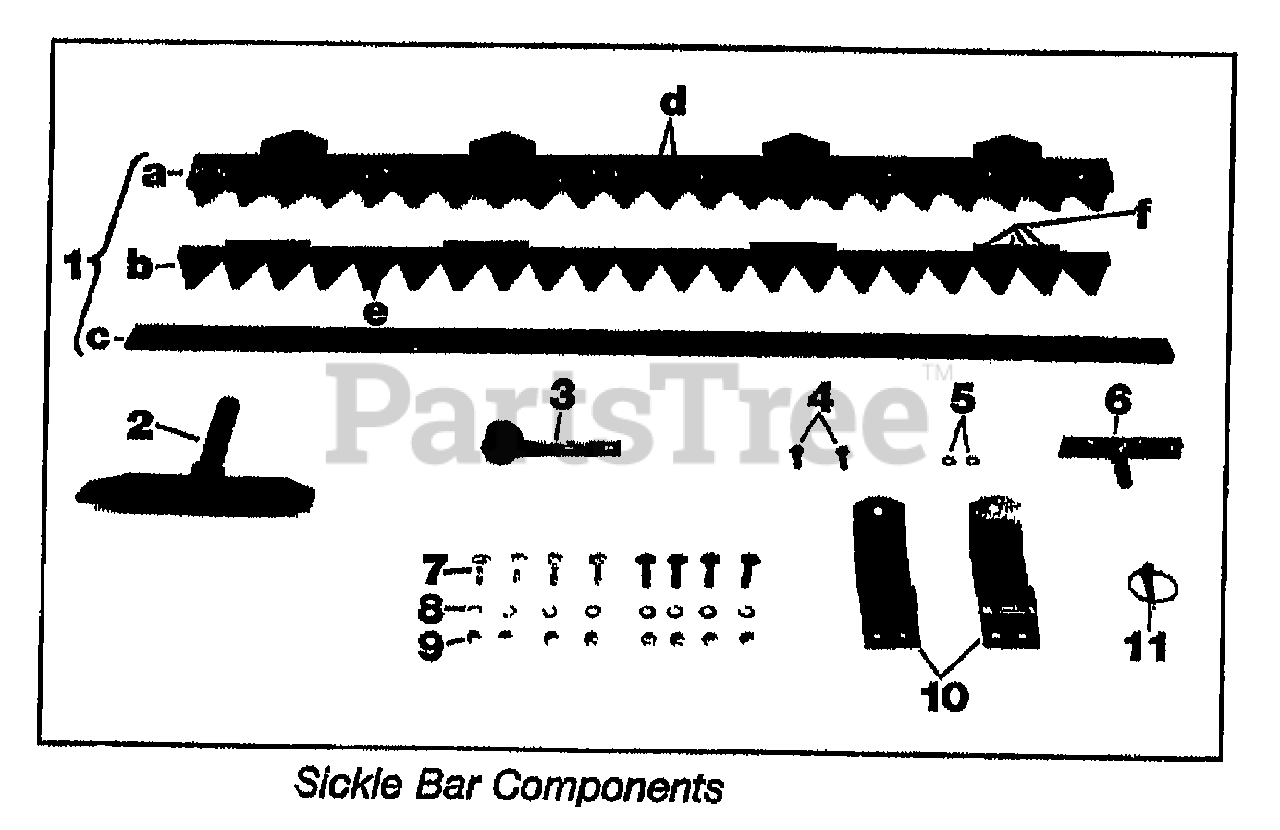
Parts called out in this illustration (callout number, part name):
1	BAR-LEDGER ASM W/BLADES
1	ASSM-38" KNIFE T/B SICKLEBAR (100CM)
1	COVER BLADE KNIFT - 100CM BLADE (38")
1	RIVETS, 18MM (ATTACHES KNIFE BLADES TO LEDGER BAR)
1	RIVETS, 14MM (ATACHES KNIFE BLADES TO CUTTER BAR)
1	RIVETS, 16MM (ATTACHES WEAR PLATES TO CUTTER BAR)
2	CUTTER BAR MOUNTING SHAFT
3	DRIVE SOCKET AND BUSHING
4	SCREW, HEX HEAD, 8MM x 20MM
5	LOCKWASHERS, 8MM
6	CUTTER BAR MOUNT
7	CARRIAGE BOLTS, 8MM x 30MM
8	WASHER, 8MM
9	LOCKNUTS, NYLON INSERT, 8MM
10	HEIGHT ADJUSTER ASSEMBLY
11	RETAINING RING
